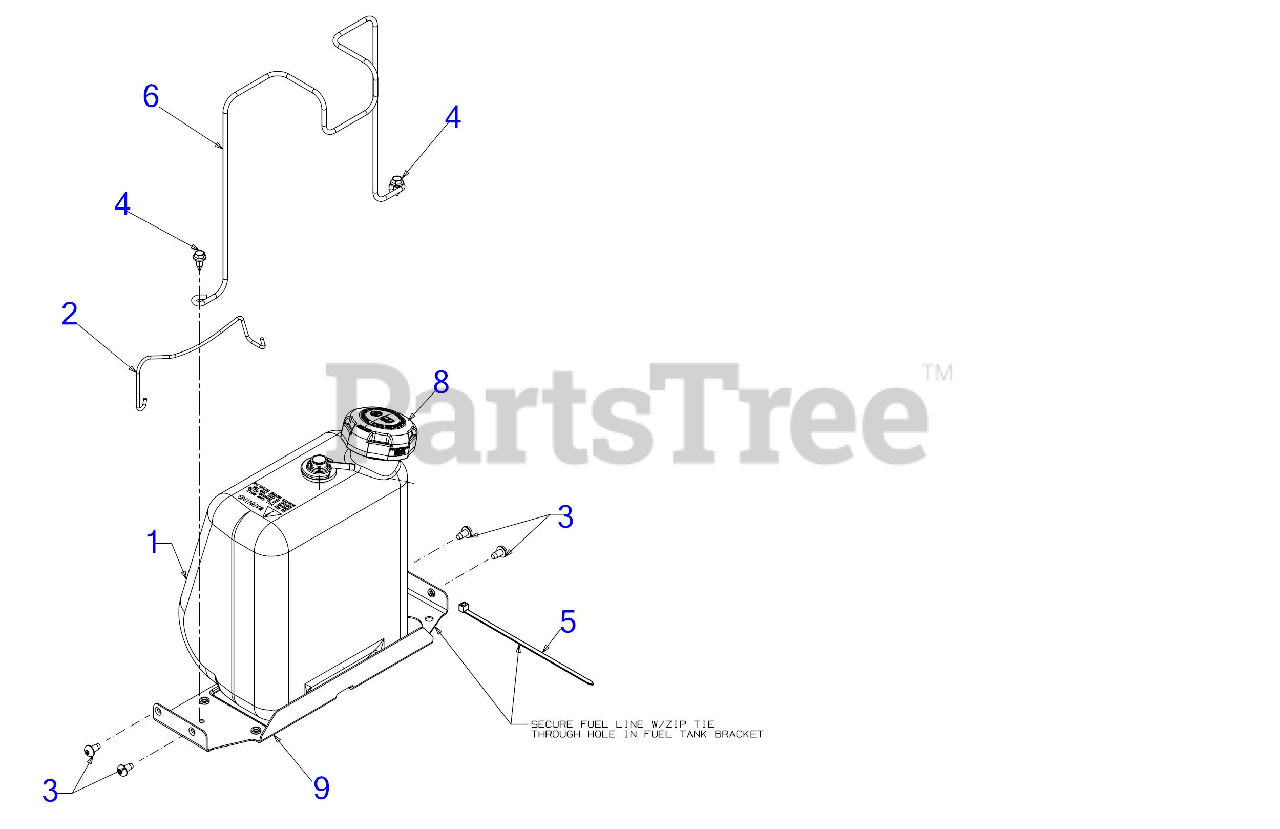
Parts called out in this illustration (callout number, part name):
1	FUEL TANK ASSEMBLY
2	BATTERY ROD ASSEMBLY
3	SCREW 1/4-20 x .5
4	SCREW 1/4-20X.625
5	7" CABLE TIE
6	FUEL TANK SUPPORT ROD -
8	FUEL CAP W/TETHER
